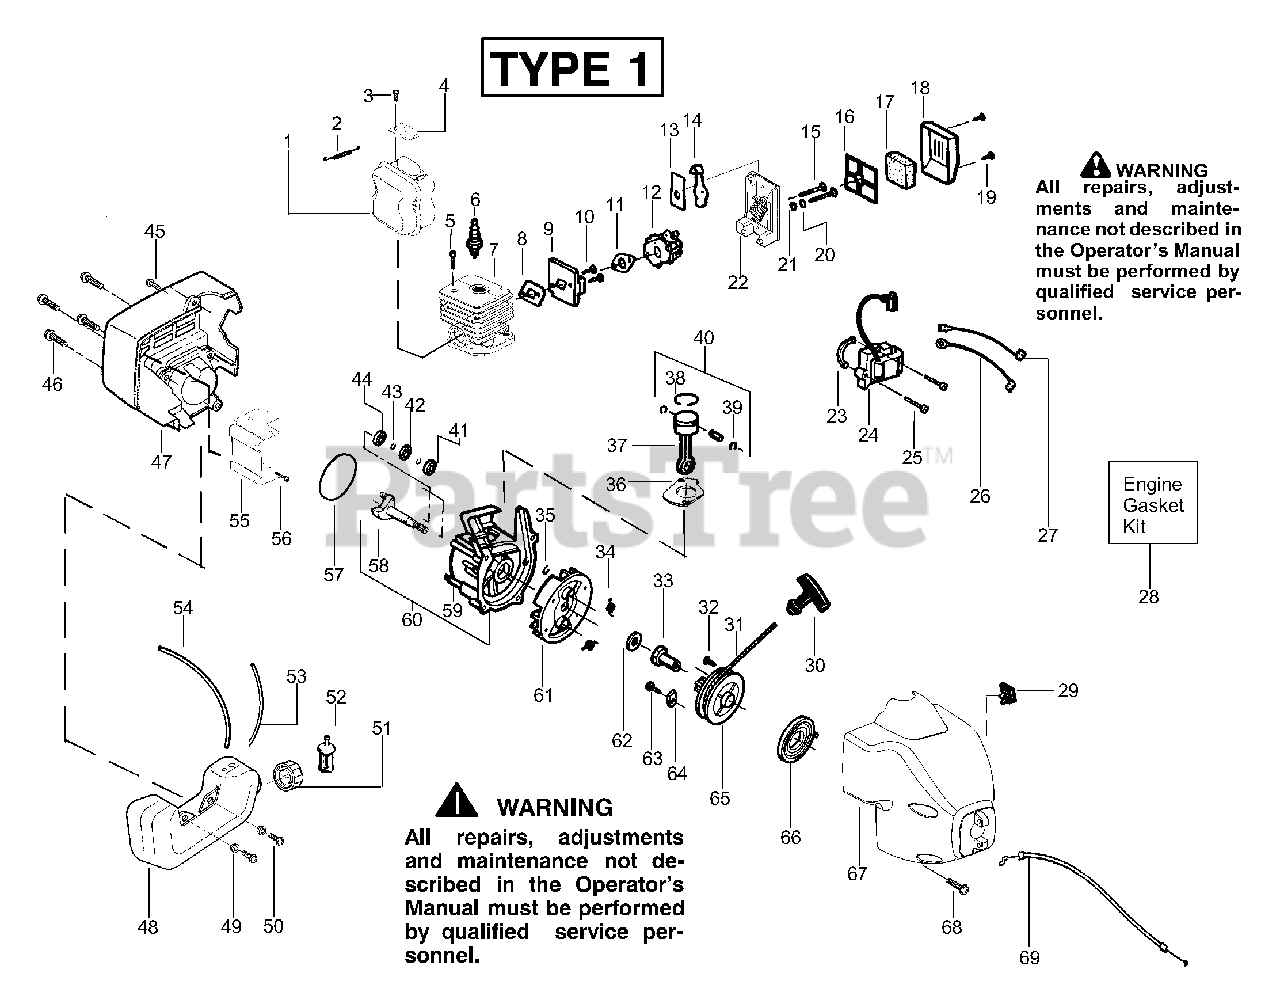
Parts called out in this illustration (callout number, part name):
1	Kit-Muffler
2	Muffler Spring
4	Screen-Spark Arrestor
5	Screw-Cylinder
6	Spark Plug (RCJ-7Y)
7	Kit-Cylinder
8	Gasket-Cylinder/Carb.
9	Carb. Adapter
10	Screw-Carb Adptr.
11	Gasket-Carb.
12	Kit-Carb. Ass'y.
13	Choke Plate
14	Choke Shutter
15	Screw-Carburetor
16	Filter Support Plate
17	Air FIlter Foam
18	Air Filter Cover
19	Screw-Air Box
20	Choke Spacer
23	Spacer-Ignit. Module
24	Ignition Module
25	Screw-Ignit. Module
26	Ground Wire Ass'y.
27	Lead Wire Ass'y.
28	Kit-Engine Gasket
29	Switch-Momentary
30	Starter Handle
31	Kit-Rope
33	Drive Coupling
34	Spring Starter Dog
35	Ret. Ring-C'case
36	Gasket-Cylinder
37	Connecting Rod Assy.
38	Piston Ring
39	Piston Pin Retainer
40	Kit-Piston
41	Outer Bearing
42	C'case Seal
43	Ret. Ring/C'shaft
44	Inner Bearing
45	Screw-Shd/Fan Hsg
46	Screw
47	Rear Shroud
48	Fuel Tank Ass'y.
49	Washer-fuel tank
50	Screw-Fuel Tank
51	Fuel Cap Assy.
52	Fuel Pickup Assy
53	Fuel Line (Small)
54	Fuel Line (Large)
55	Shield-Heat
56	Screw-Heat Shield
57	O-ring-C'case
58	Crankshaft Ass'y.
59	Crankcase Assy.
60	C'case/C'shaft Assy.
61	Flywheel Ass'y.
62	Washer-Flat
63	Screw-Pulley
64	Retainer-Pulley
65	Kit-Starter Pulley
66	Starter Spring
67	Assy.-Fan Hsg.
68	Screw
69	Assy-Throttle Cable
